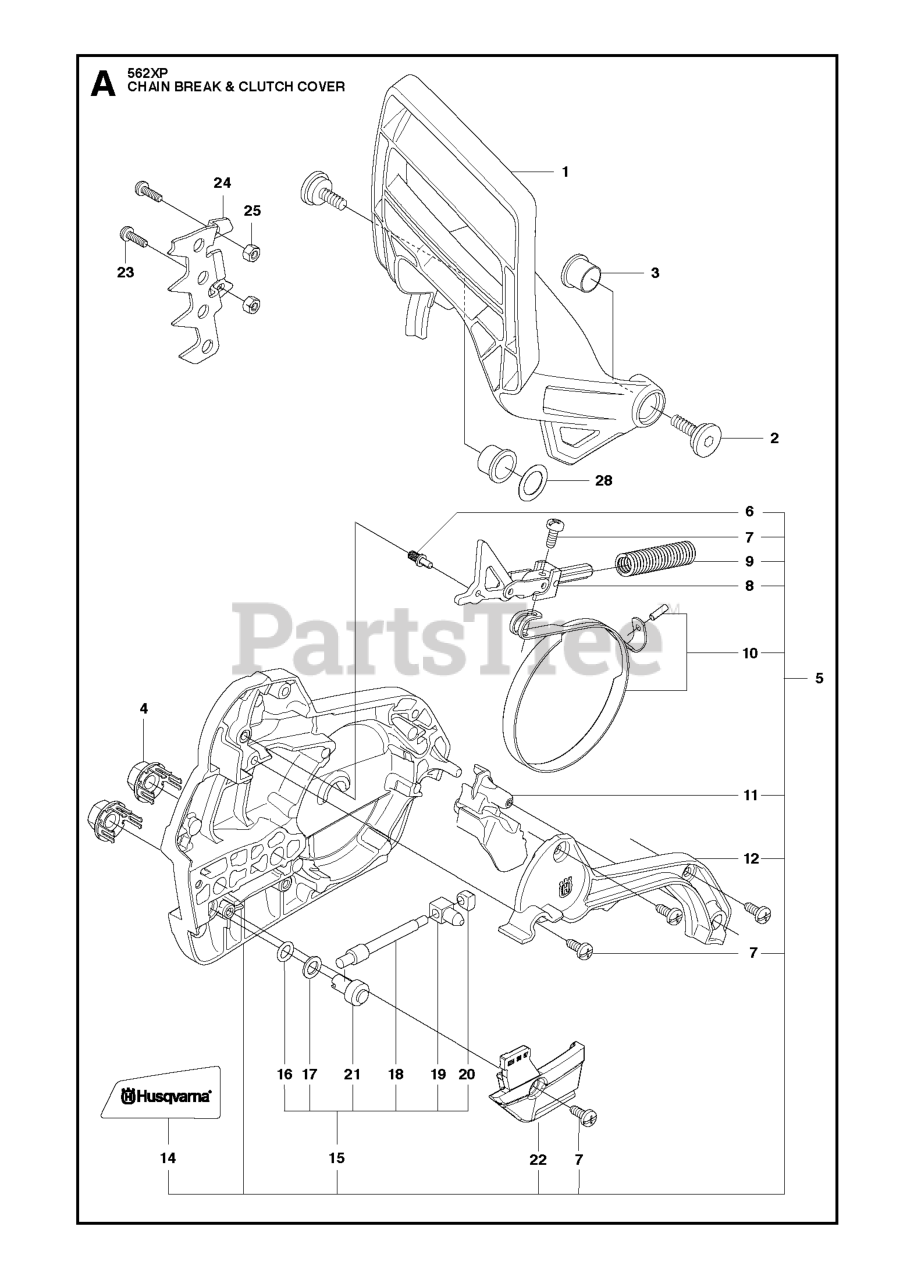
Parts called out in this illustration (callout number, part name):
1	HAND GUARD
4	NUT RETAINER ASSY
5	CLUTCH COVER ASSY
6	PIN
7	SCREW
8	KNEE JOINT ASSY
9	SPRING
10	BRAKE BAND ASSY
11	GUARD
12	COVER
14	LABEL
15	CHAIN TENSIONER KIT
16	O-RING
17	WASHER
18	WORM SCREW
19	PAWL RIGHT HAND THREADED
20	PAWL
21	WORM WHEEL
22	CHAIN GUIDE
24	SPIKE OUTER
28	WASHER STEEL
